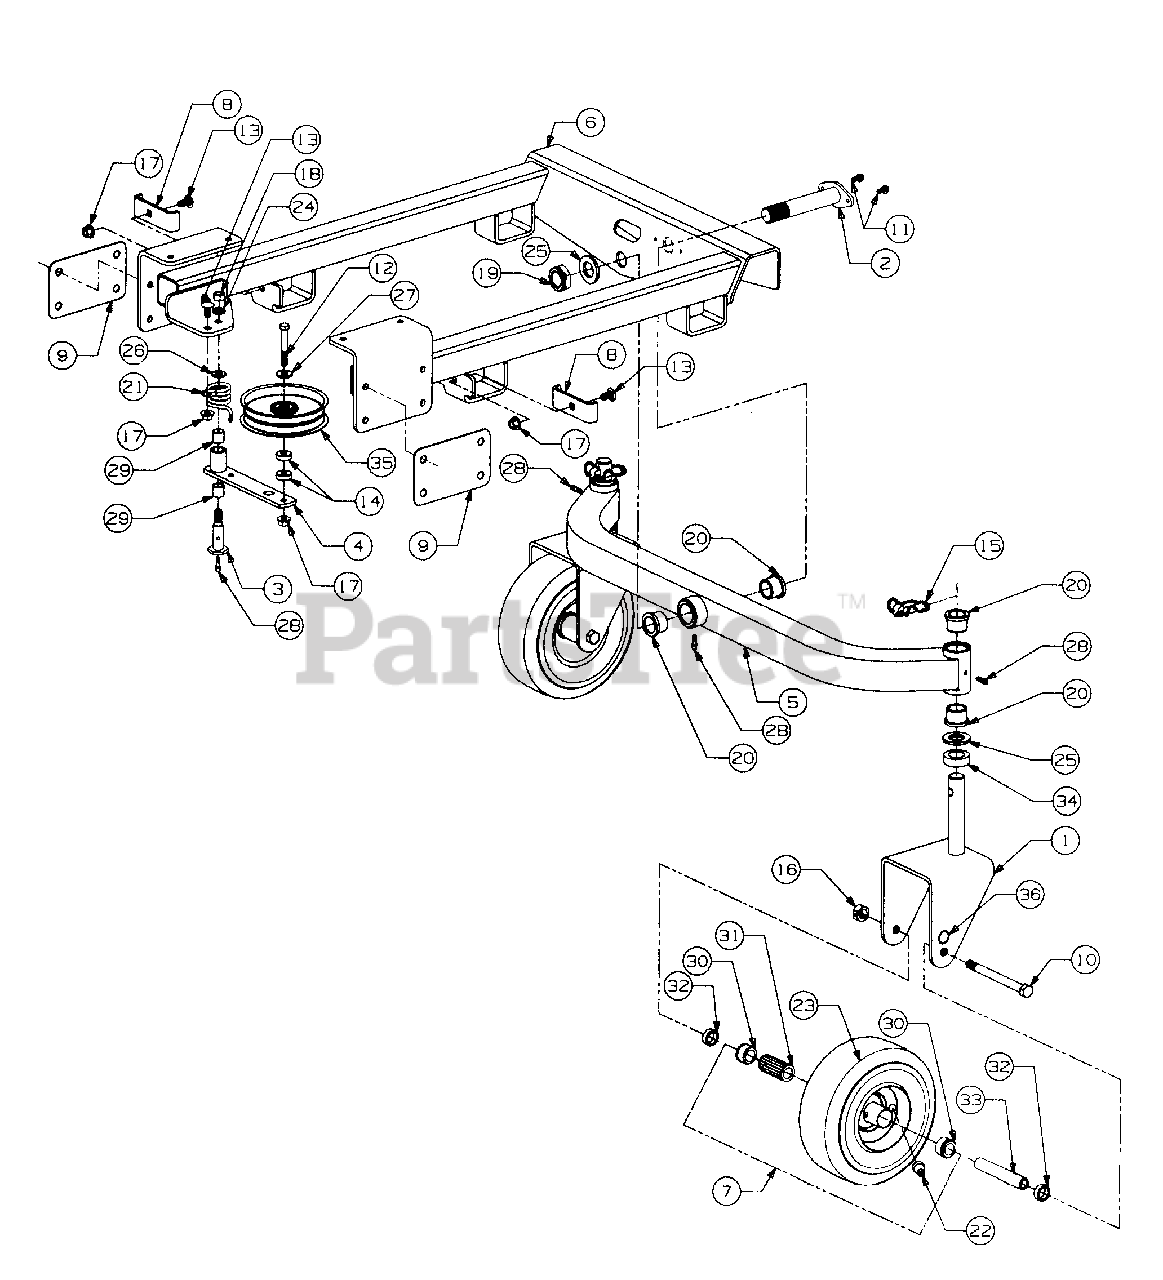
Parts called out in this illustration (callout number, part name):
2	Pin, Axle Pivot
3	Bolt, Shoulder
4	Arm Assy, Idler
5	Axle Assy, Front
7	Wheel Assy, Caster
8	Stop, Wear Bar
10	Screw, Hex Cap, 1/2-20 X 5.50 Lg
11	Screw, Hex Wash Hd TT-Tap, 1/4-20 X .50 Lg
12	Screw Hex Cap, 3/8-16 X 2.5 Lg GR5
13	Bolt, Sht Nk Carriage, 3/8-16 X .75 Lg GR5
14	Spacer, .380 X 1.0 X .320
15	Pin, Klik
16	Nut, Hex Center Lock, 1/2-20
17	Nut, Hex, Flanged Lock, 3/8-16
18	Nut, Hex 7/16-14 GR5
19	Nut, Hex Lock, 1-14
20	Bearing, Flange
21	Spring, Torsion
22	Valve, Tubeless Air
23	Tire, Smooth, 9.0 X 3.50 X 4
24	Washer, Lock, 7/16
25	Washer, Special
26	Washer, Flat, .469 X .875 X .105 Thk
27	Washer, Flat, .406 X 1.0 X .105 Thk
28	Fitting, Lube
29	Bearing, Sleeve
30	Bearing, Graf Oil Flange
31	Bearing, Roller
32	Spacer, .790 ID X .347 Lg
33	Spacer, Wheel
34	Spacer, 1.015 X 1.62 X .50 Lg
35	Pulley, 5" Idler
36	Label, Inflation
